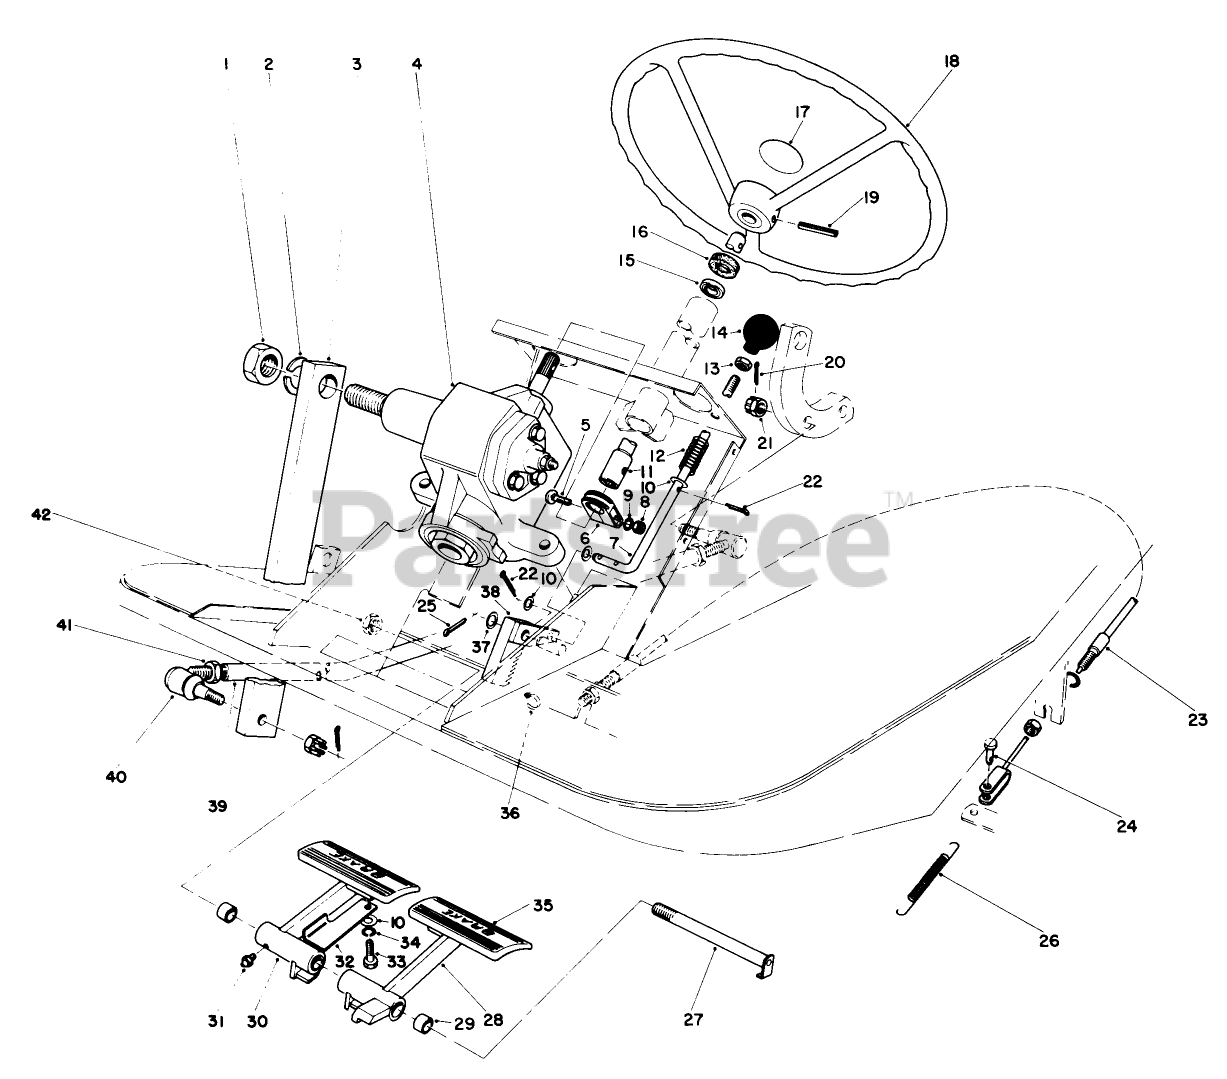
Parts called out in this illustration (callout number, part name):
1	NUT-JAM
2	WASHER-LOCK/SP
3	Pitman Arm
4	Steering Gear
5	7/16-14 X 1-3/4 BOLT
6	STRG COUPLING CLAMP
7	Rod Brake Latch
8	NUT-HEX
9	WASHER-LOCK
10	WASHER-FLAT
11	Shaft-Steering
12	Spring
13	NUT-HEX
15	BALL BRG
16	COVER-DUST
17	STEERING WHEEL CAP
18	STEERING WHEEL
19	PIN-ROLL
20	PIN-COTTER
21	NUT-SLOTTED
22	PIN-COTTER
23	RH BRAKE CABLE ASM
24	PIN-CLEVIS
25	PIN-COTTER
26	SPRING-EXTENSION
27	Pin
28	Brake Pedal L.H. (Incl. Ref. #29 & 31)
29	BUSHING
30	Brake Pedal R.H. (Incl. Ref. #29 & 31)
31	FITTING-GREASE
32	Latch Parking Brake
33	SCREW-HH
34	WASHER-LOCK
35	PAD-BRAKE
36	TIE-CABLE
37	WASHER-FLAT
38	Rack
39	FRONT STEERING TUBE B
40	Socket Assembly R.H. (Incl. Ref. #21)
41	NUT-JAM
42	NUT-LOCK, NI
